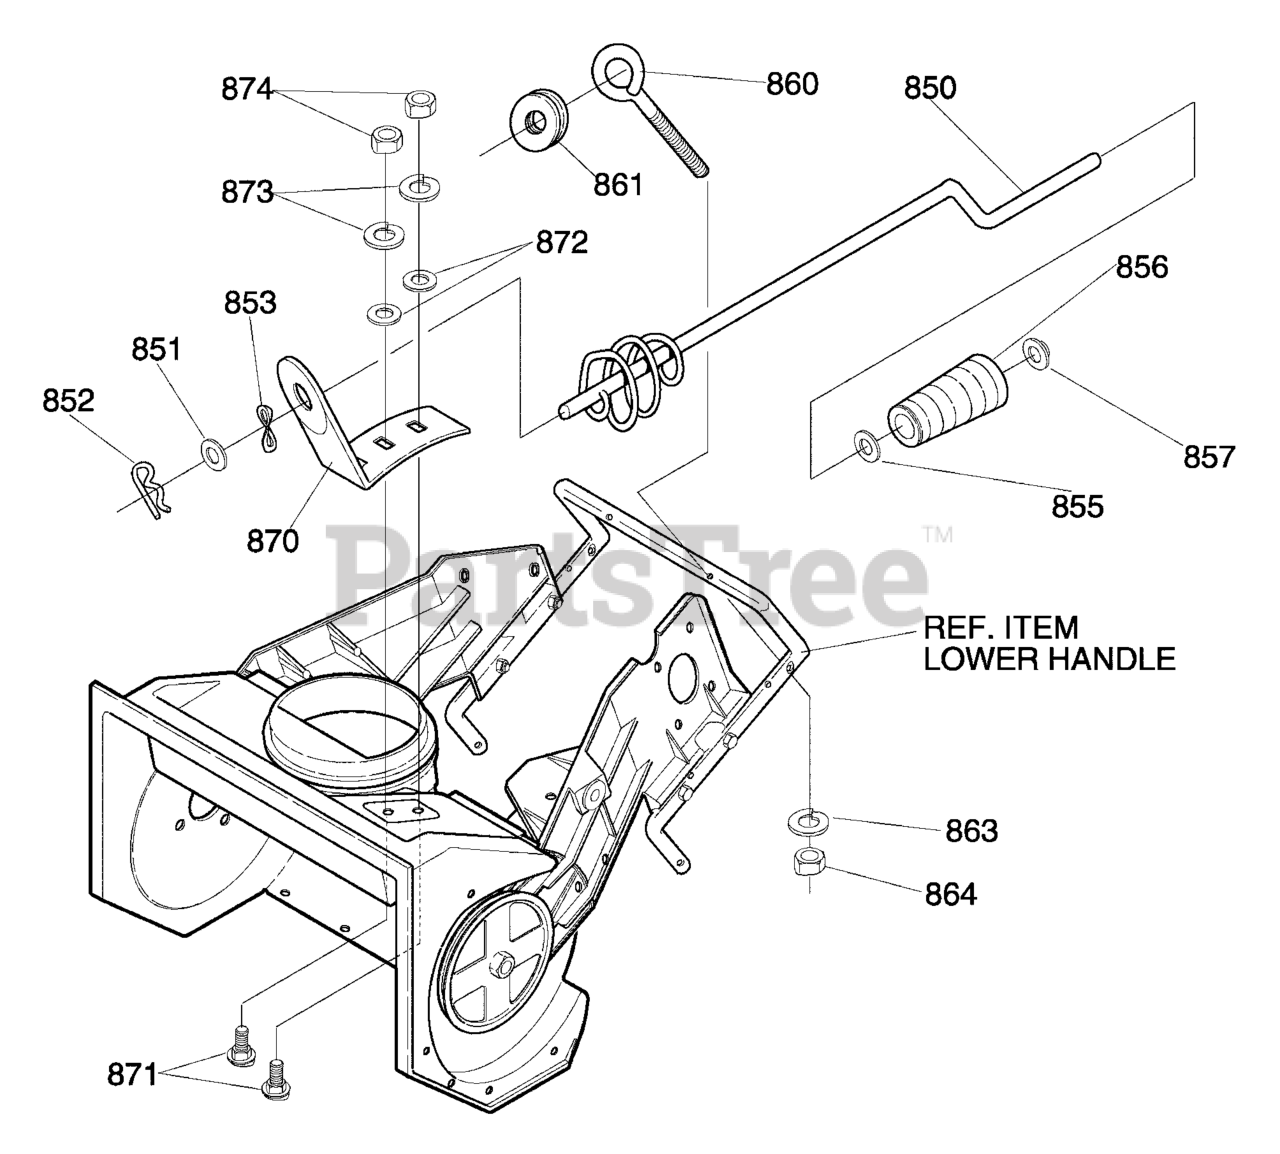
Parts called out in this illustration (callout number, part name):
850	ROD, ASSY UPPER CHUTE CONTROL
851	WASHER, FLAT .406X.81X.066
852	PIN, COTTER
853	WASHER, CURVED SPRING
855	WASHER, FLAT .406X.81X.066
856	KNOB, SLEEVE
857	NUT, PUSH
860	BOLT, EYE 3/8-16X2.00
861	GROMMET, EYE BOLT
863	WASHER
864	NUT, HEX JAM 3/8-16
870	BRACKET, CHUTE ROTATE
871	BOLT, CARRIAGE 5/16-18X.75
872	WASHER, FLAT .349X.69X.066
873	WASHER .328X.60X.09
874	NUT, HEX 5/16-18
